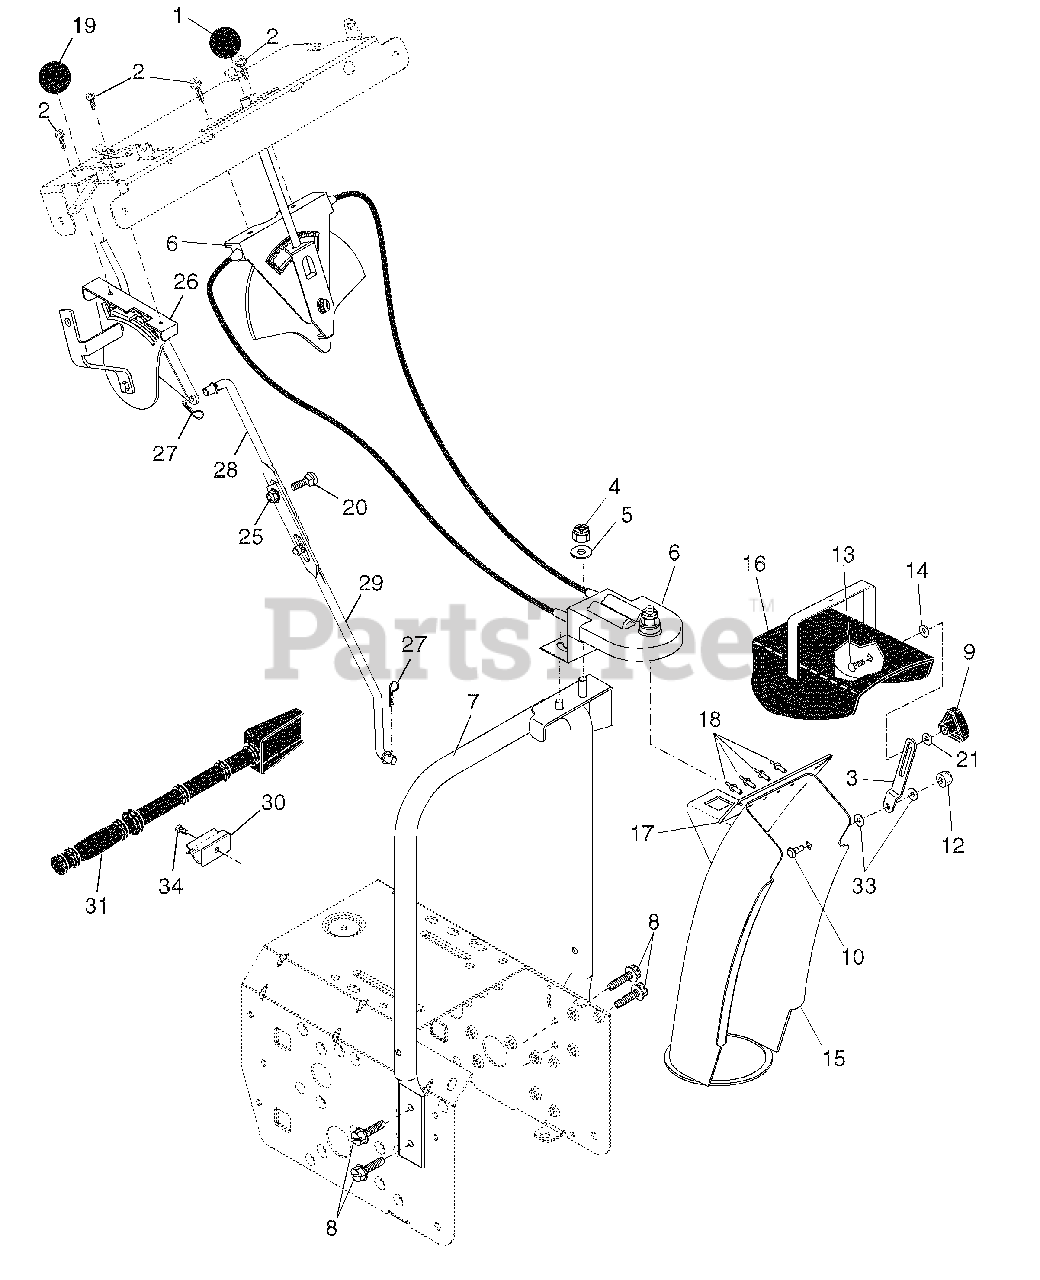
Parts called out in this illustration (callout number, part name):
1	Knob, Lever
2	Screw #10-24 x 5/8
3	Strap, Slotted
4	Nut, Lock 3/8-16
5	Washer, Flat 3/8
6	Control Assembly, Chute Rotater
7	Support, Pivot
8	Screw, Hex Head 5/16-18 x 3/4
9	Knob, Deflector
10	Bolt, Shoulder
12	Nut, Lock 1/4-20
13	Bolt, Carriage 5/16-18
14	Washer, Nylon
15	Chute Assembly
16	Deflector Assembly
17	Seal, Deflector
18	Rivet, Blind
19	Knob, Speed Control Lever
20	Bolt, Carriage 5/16-18 x 3/4
21	Washer, Flat 5/16
25	Nut, Lock 5/16-18
26	Lever Assembly, Speed Control
27	Retainer, Hairpin
28	Rod, Upper, Speed Control
29	Rod, Lower, Speed Control
30	Clamp, Clean-Out Tool
31	Tool, Clean-Out
33	Screw HI-LO
